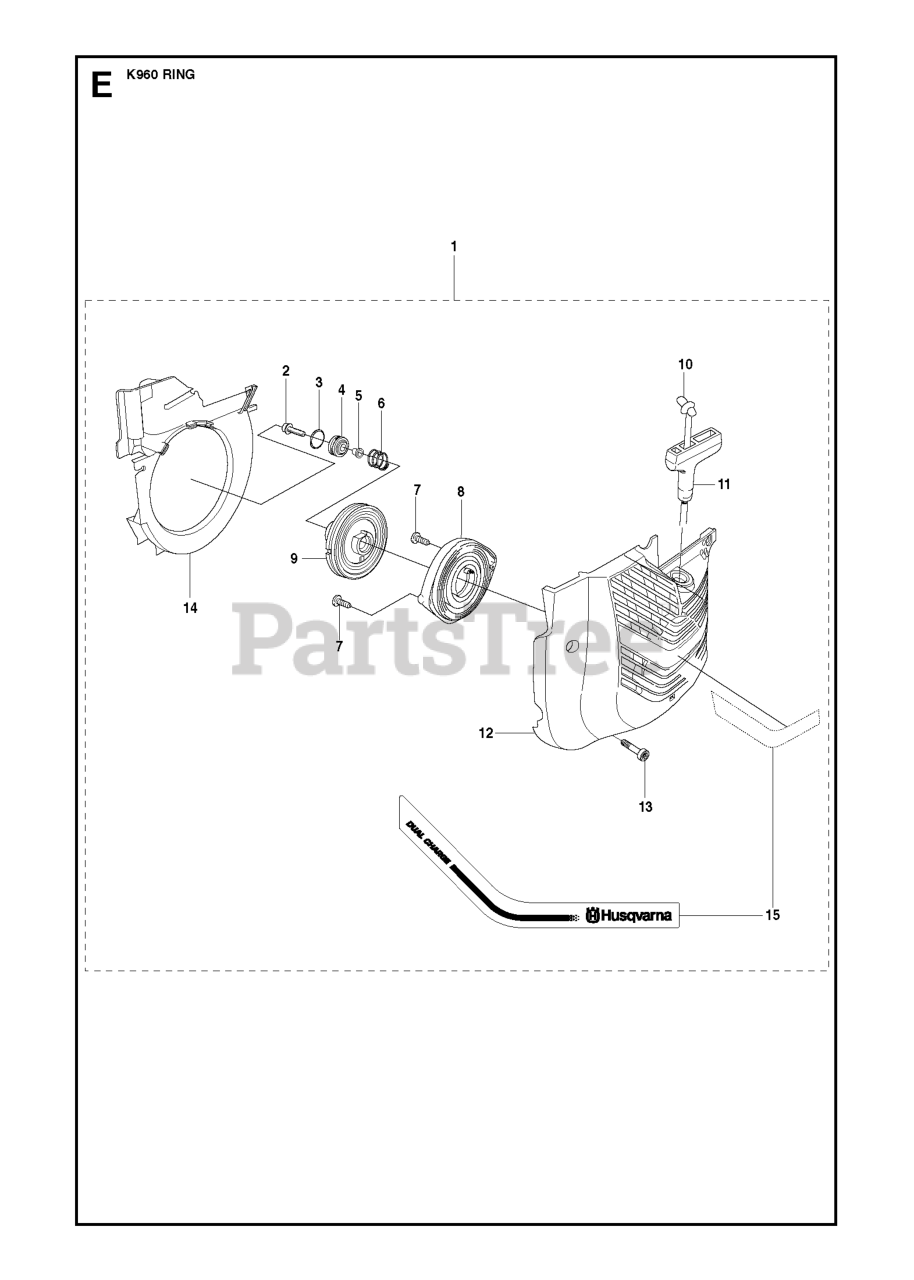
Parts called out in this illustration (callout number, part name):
1	%STARTER
2	SCREW
4	RP WASHER
8	RETURN SPRING
9	STARTER PULLEY
10	STARTER ROPE 50 M
10	STARTER ROPE
11	STARTER HANDLE
12	STARTER COVER
14	RP COOLING AIR CONDUCTOR
